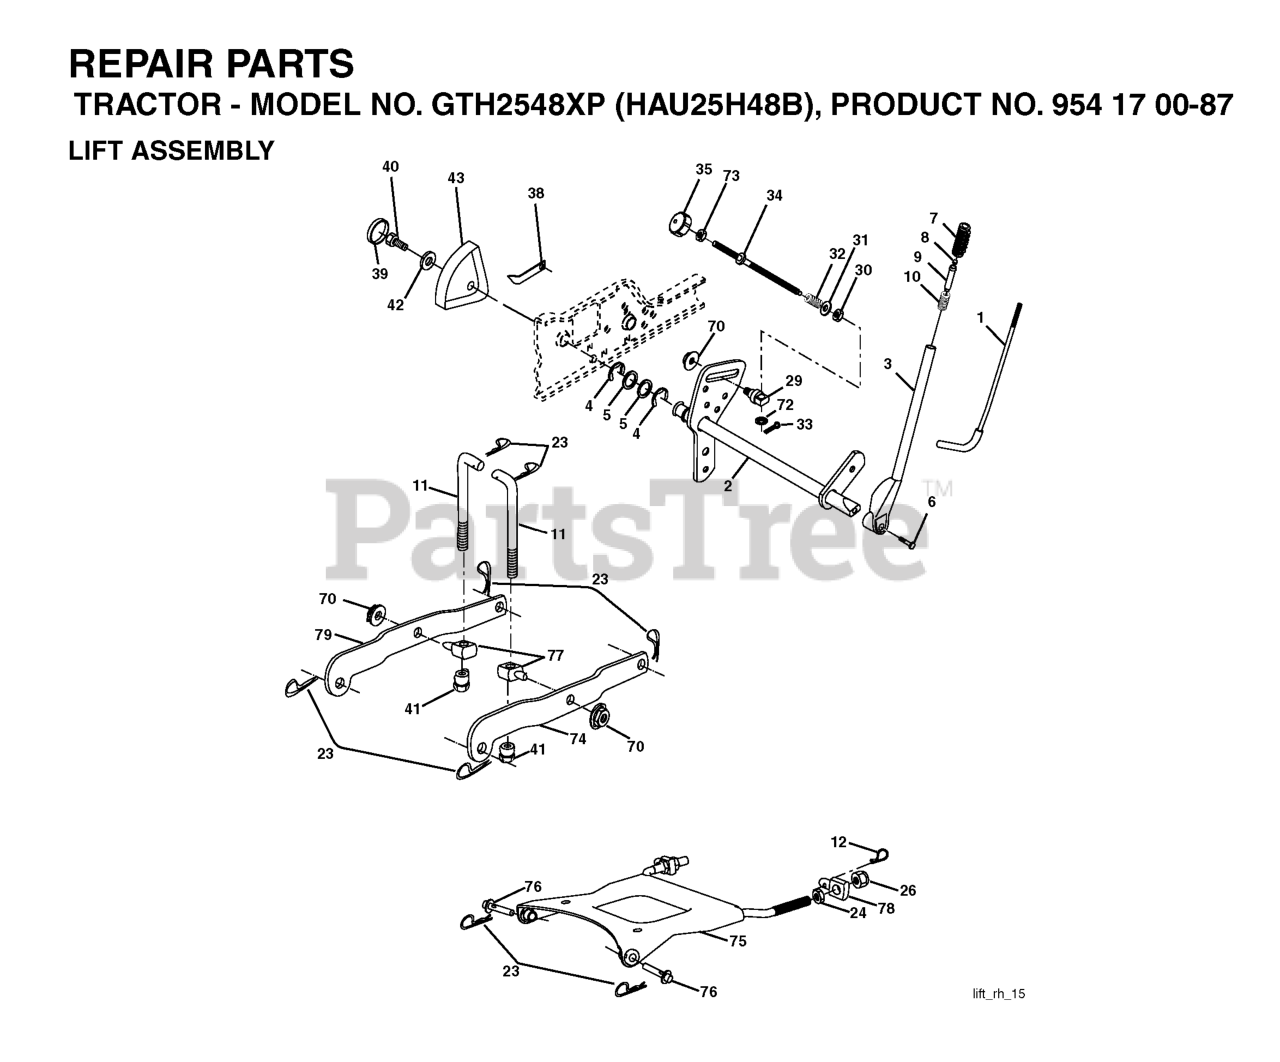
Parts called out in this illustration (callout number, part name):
1	LEVER ROD LT
2	SHAFT ASM., LIFT VGT
3	LEVER ASSY-LIFT RH
5	Washer 29/32 x 1 - 1/4 x 16 Ga.
6	Bolt, Fin Hex 3/8-16 x 1-1/12
7	GRIP HANDLE
8	PLUNGER BUT KIT
9	PLUNGER BUT KIT
10	SPRING 0.620D X 2.125
11	LIFT LINK
12	SPRING RETAINER
23	RETAINER-SPRNG RB
24	NUT.HEX.JAM.1/2-13
26	NUT.LK.W/WSH.1/2.
32	SPRING.COMP.INF.H
33	COTTER PIN
34	ROD.LIFT.ADJUSTABLE
35	KNOB INF 3/8-16
38	POINTER, HEIGHT INDICATOR(2 2)
40	SCREW 5/16-18X1
41	NUT, LIFT LINK 7/16-20
43	HEIGHT INDICATOR
70	NUT
72	NUT PUSH M
73	NUT
74	ARM SUSP REAR RH
75	PLATE ASM SUSP FRONT
76	PIN.FLANGE
79	ARM SUSP. REAR LH
